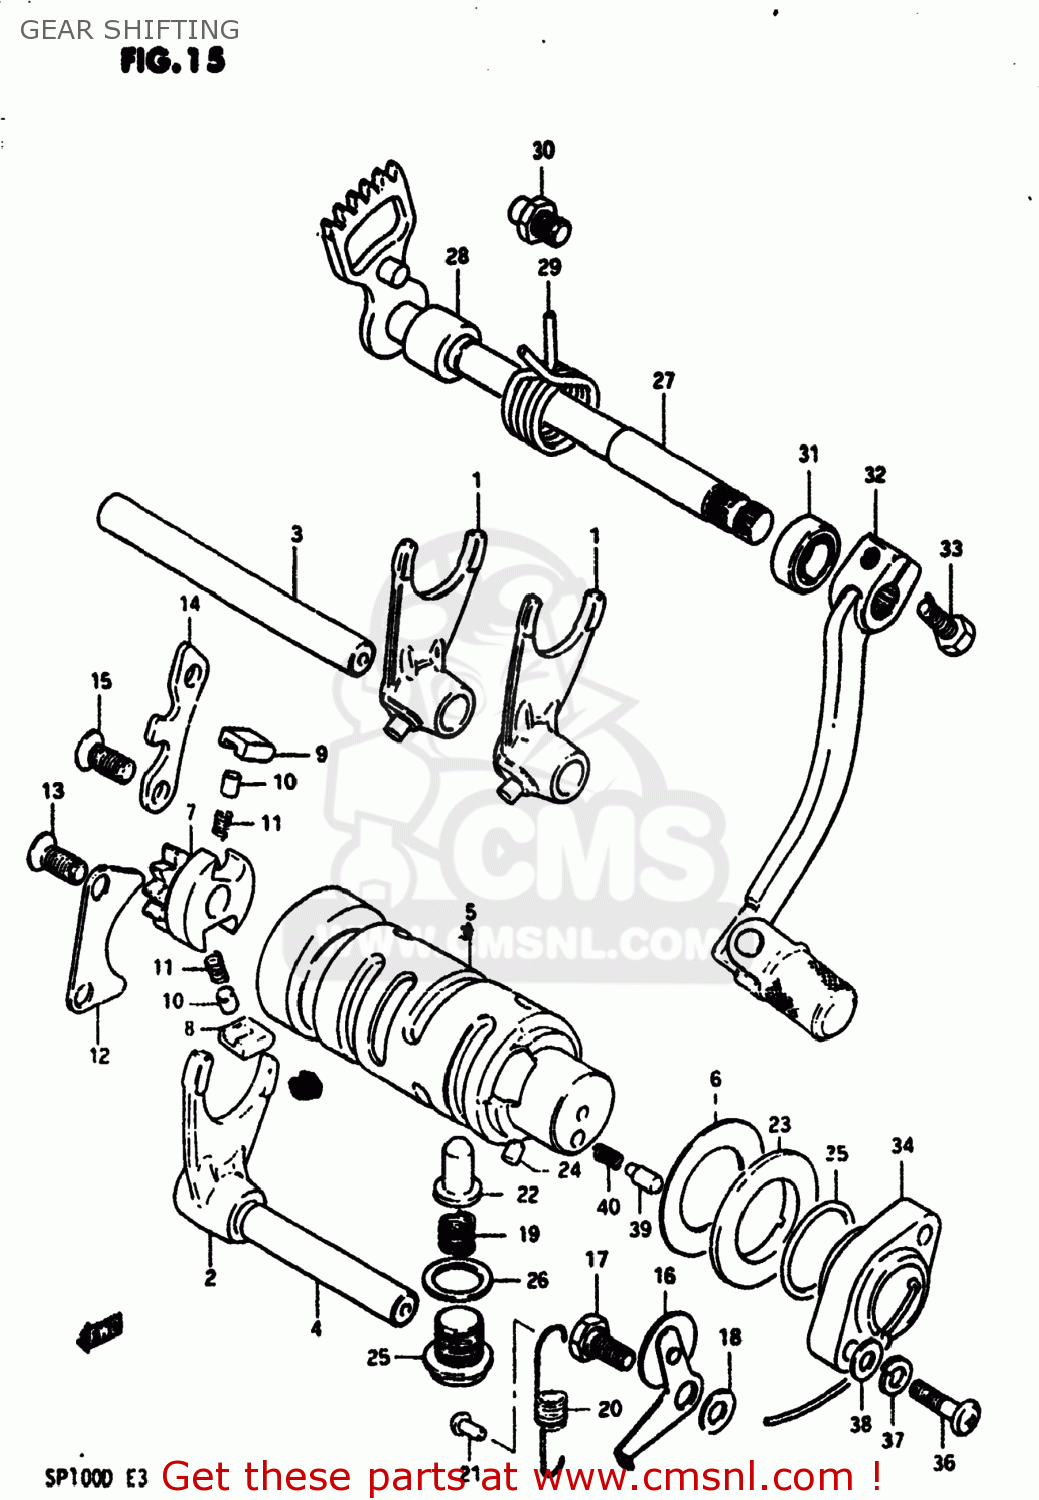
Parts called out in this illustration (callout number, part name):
1	FORK,GEAR SHIFT NO.1
2	FORK,GEAR SHIFT NO.3
3	SHAFT,GEAR SHIFT FORK
4	SHAFT,GEAR SHIFT FORK
5	CAM,GEAR SHIFT
6	WASHER,THRUST
7	RETAINER,GEAR SHIFT CAM
8	PAWL,GEAR SHIFT NO.1
9	PAWL,GEAR SHIFT NO.2
10	PIN(5X8)
11	SPRING
12	LIFTER,GEAR SHIFT PAWL
13	SCREW
14	GUIDE,GEAR SHIFT CAM
15	SCREW
16	STOPPER,GEAR SHIFTING
17	BOLT
18	WASHER
19	SPRING
20	SPRING
21	RIVET
22	STOPPER,GEAR SHIFT CAM NO.2
23	PLATE,GEAR SHIFT CAM STOPPER
24	PIN 4X6
25	PLUG (14X12)
26	GASKET(14X19.2X2) (NAS)
27	SHAFT,GEAR SHIFT
28	SPACER(12X20X15.3)
29	SPRING
30	STOPPER,GEAR SHIFT CAM
31	OIL SEAL
32	LEVER ASSY,GEAR SHIFT
33	BOLT
34	TERMINAL BASE,NEUTRAL SWITCH
35	O-RING (D:2.4 ID:26.2)
36	SCREW 5X20
37	LOCK WASHER
38	WASHER
39	PIN(5X15.5)
40	SPRING
